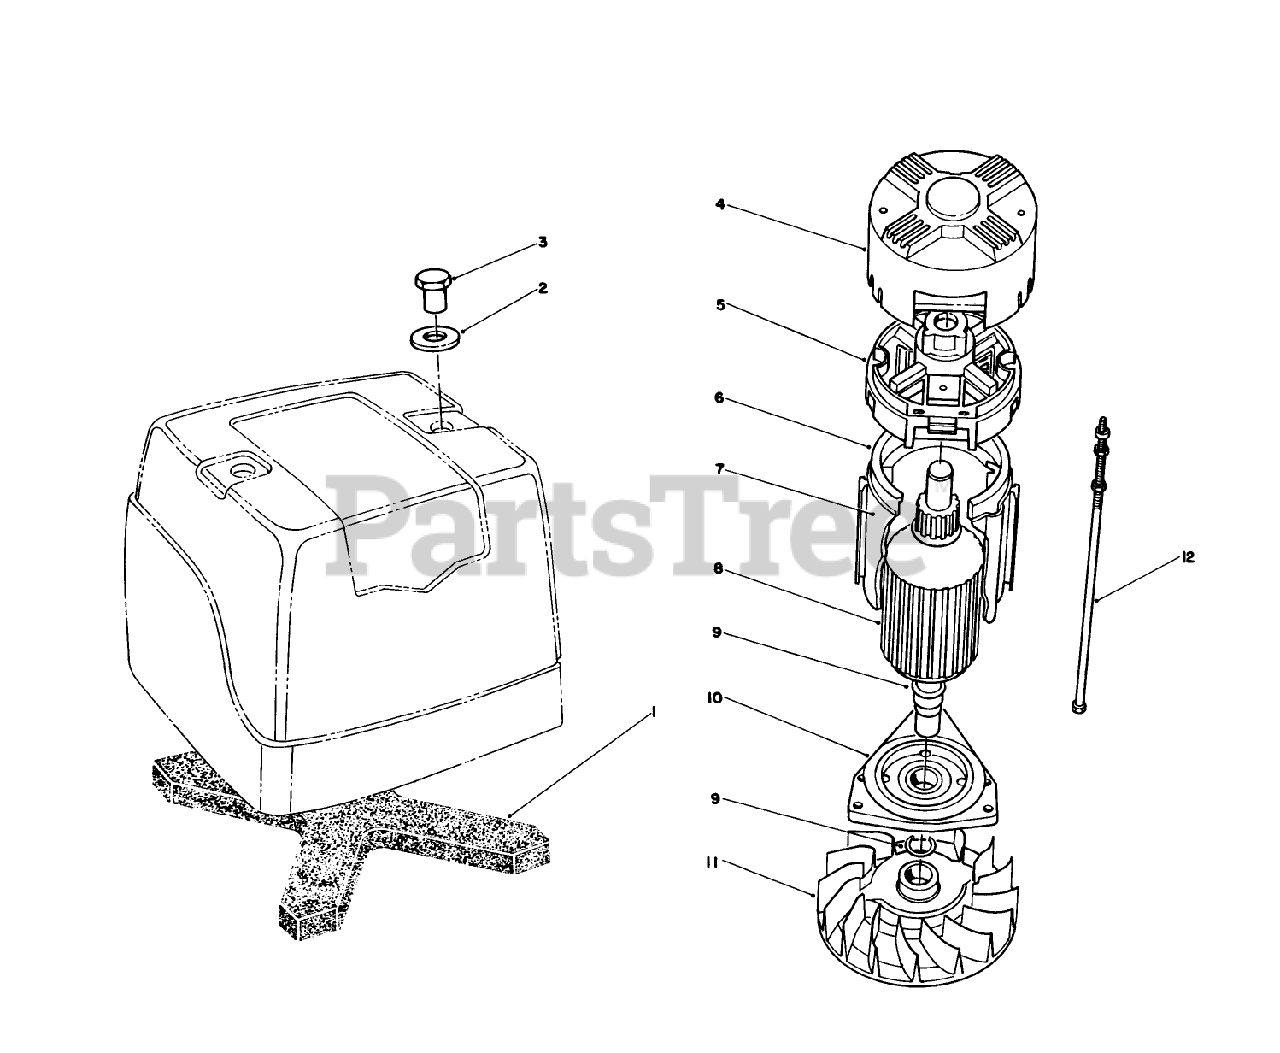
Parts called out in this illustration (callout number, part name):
1	Filter
2	Washer
3	Nut-Hex
4	End Cap-Brush
5	Brush Box Group (Includes: 490834 Brush Pin Group)
6	Housing Assembly
7	Insulator Group-Housing
8	Armature Group
9	Ring-Retaining
10	Spacer
12	Bolt-Thru (Includes Two Sets)
